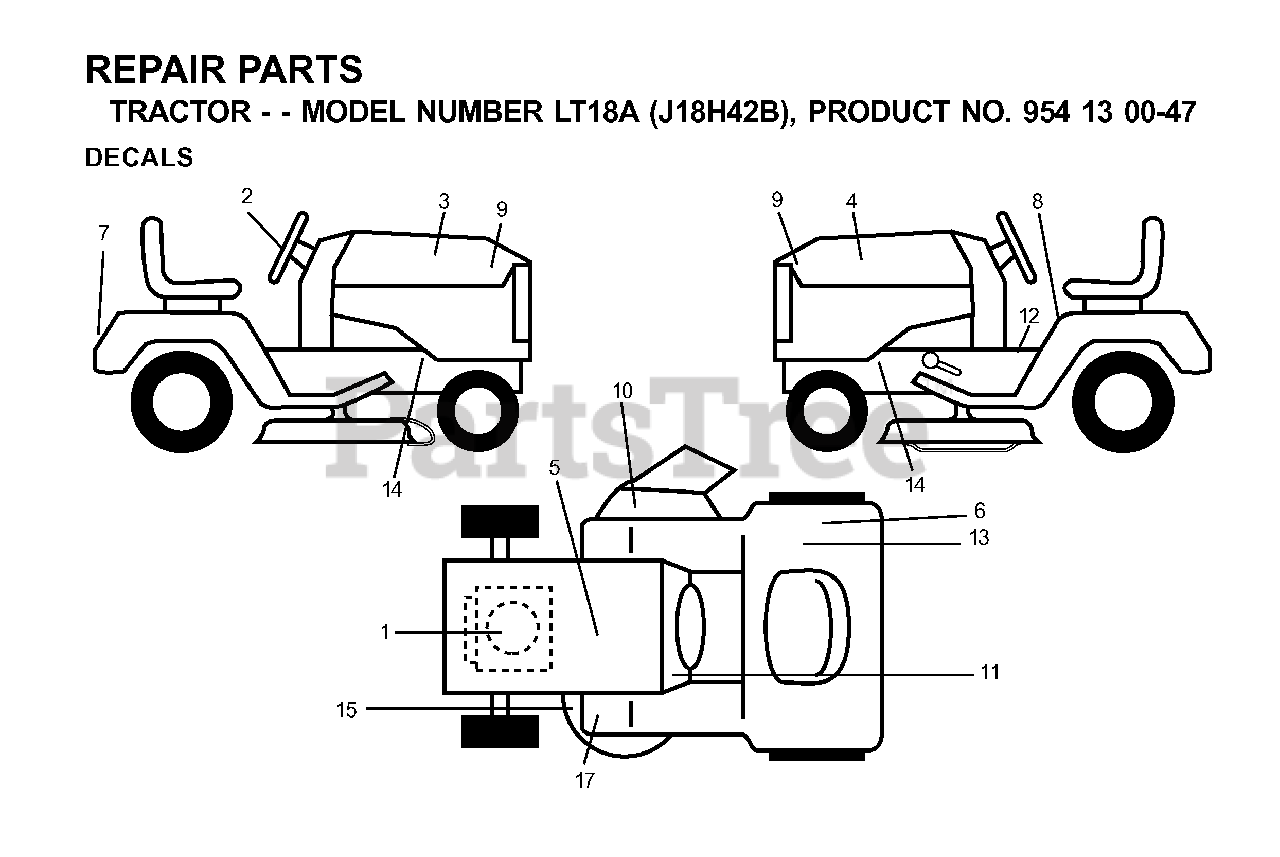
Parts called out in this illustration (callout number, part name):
5	DECAL BTRY SYMBOLS
6	DECAL CERTIFICATION
8	DECAL READ OWNER'S MAN SYMS
10	DECAL MOWER CUT/FINGER
12	DECAL PARK BRAKE
13	DECAL EUROPE STANDARD CE
15	DECAL V BELT SCHEMATIC
